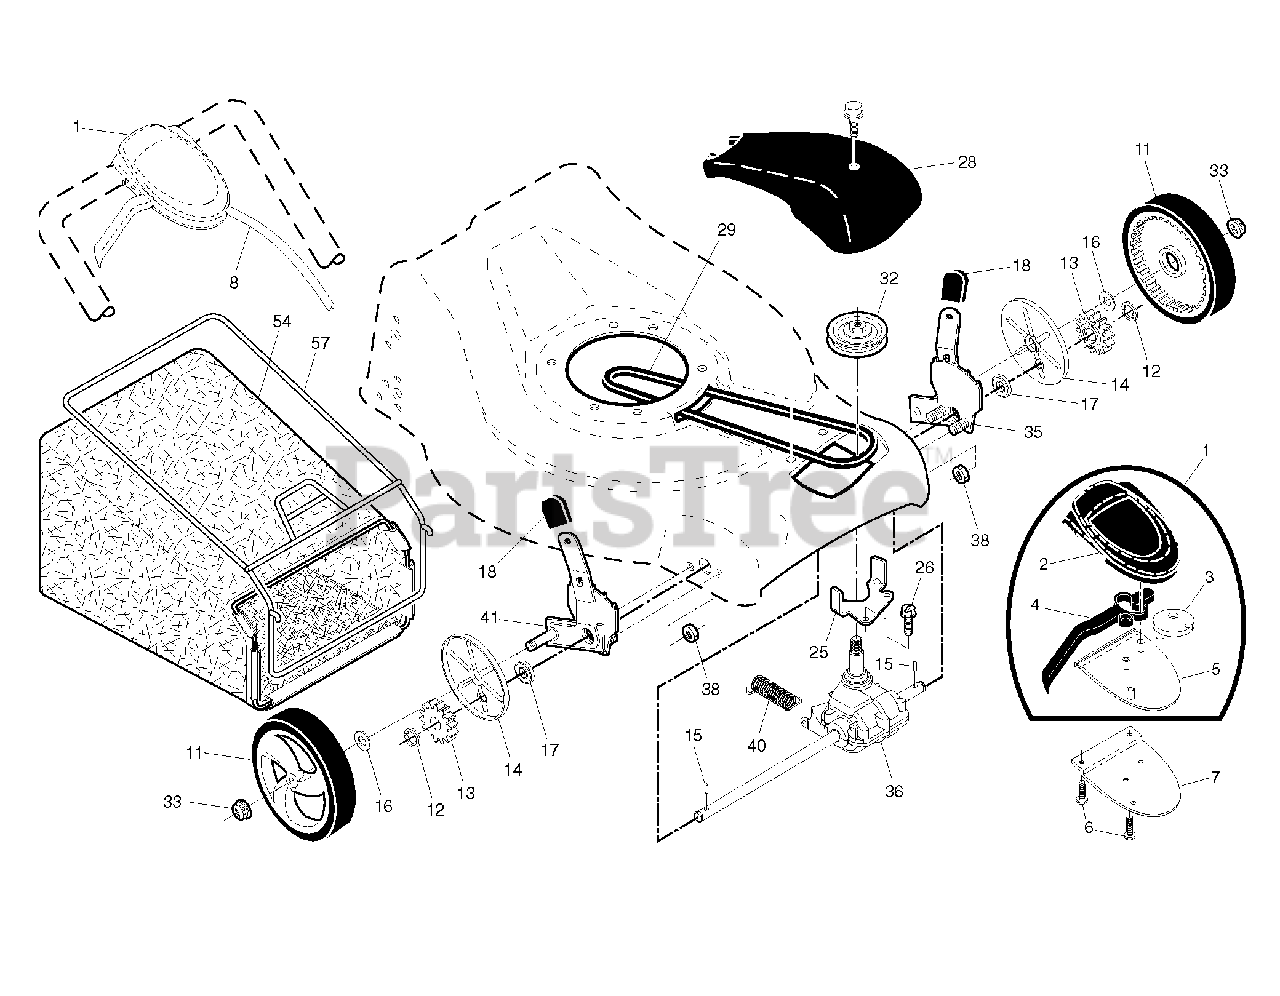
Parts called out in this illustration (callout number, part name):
2	COVER, TOP DRIVE CONTROL
3	PULLEY.CAM.DRIVE.CONTROL.EZ
5	COVER BOTTOM DRIVE CNTRL BLACK
6	SCREW, PHILLIPS HEAD 10 X 5/8
7	BRACKET.DRIVE.CONTROL.MOUNT
8	CABLE ASSEMBLY, DRIVE
12	E-RING 7/16 RE
13	PINION.14.TEETH.FGD
14	COVER.DUST.WHEEL
15	PAWL, DRIVE
16	WASHER FLUT
17	BEARING
18	SELECTOR KNOB
25	BELT KEEPER
27	SCREW, HEX HD TAPPING #10-24 1
29	BELT.DRIVE.FG
32	RP PULLEY.DRIVE.EZ
33	NUT.HEX.FLANGE.3/8-16.LOCKNUT
35	RP KIT, WHEEL ADJUSTER, LH
36	TRANSMISSION.21.FGD.HT.VST
38	LOCKNUT
41	KIT, WHEEL ADJUSTER, RH
57	FRAME.GBAG.21.FWGD
